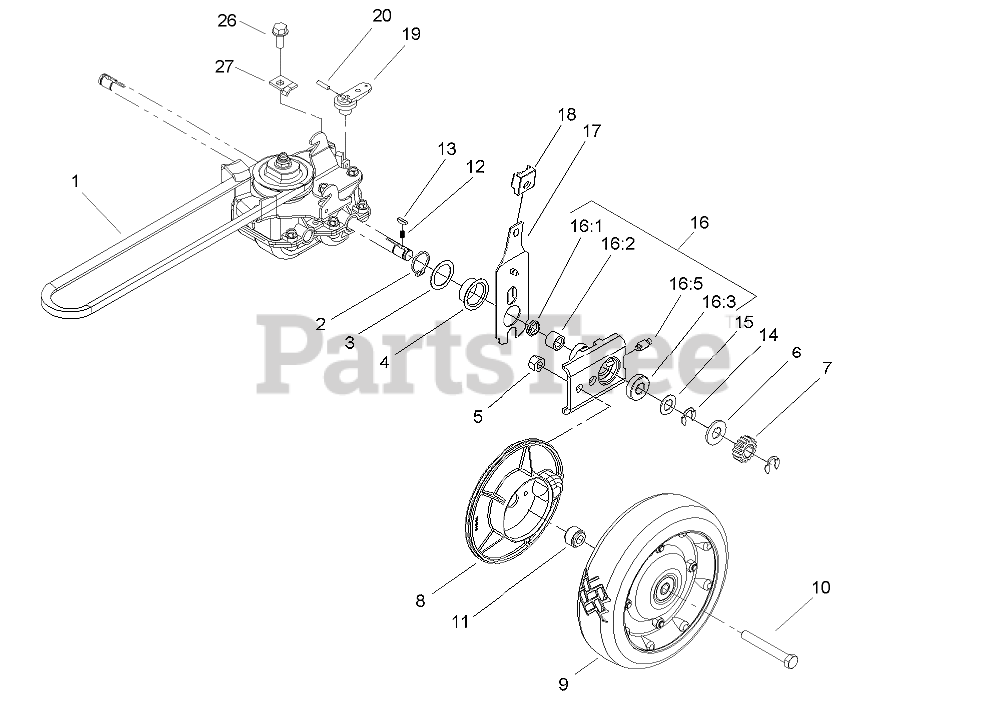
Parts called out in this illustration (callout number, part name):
1	V-BELT
2	RING-RETAINING
3	WASHER
4	CAP-END
5	NUT-LOCK, CONE
6	WASHER-THRUST, OUTER
7	GEAR-PINION
8	COVER-WHEEL
9	WHEEL AND TIRE ASM
10	SCREW-HH
11	SPACER-COVER, WHEEL
12	SPRING-COMPRESSION
14	RING-RETAINING
15	WASHER-THRUST, OUTER
16	PIVOT ARM ASM
16:1	SEAL-OIL
16:2	BEARING-ROLLER
16:3	BEARING-WHEEL
17	REAR SPRING ARM ASM
18	KNOB-ARM
19	LEVER-SHIFT
20	PIN-COIL
26	SCREW-HWHTF
27	CLAMP-CABLE
